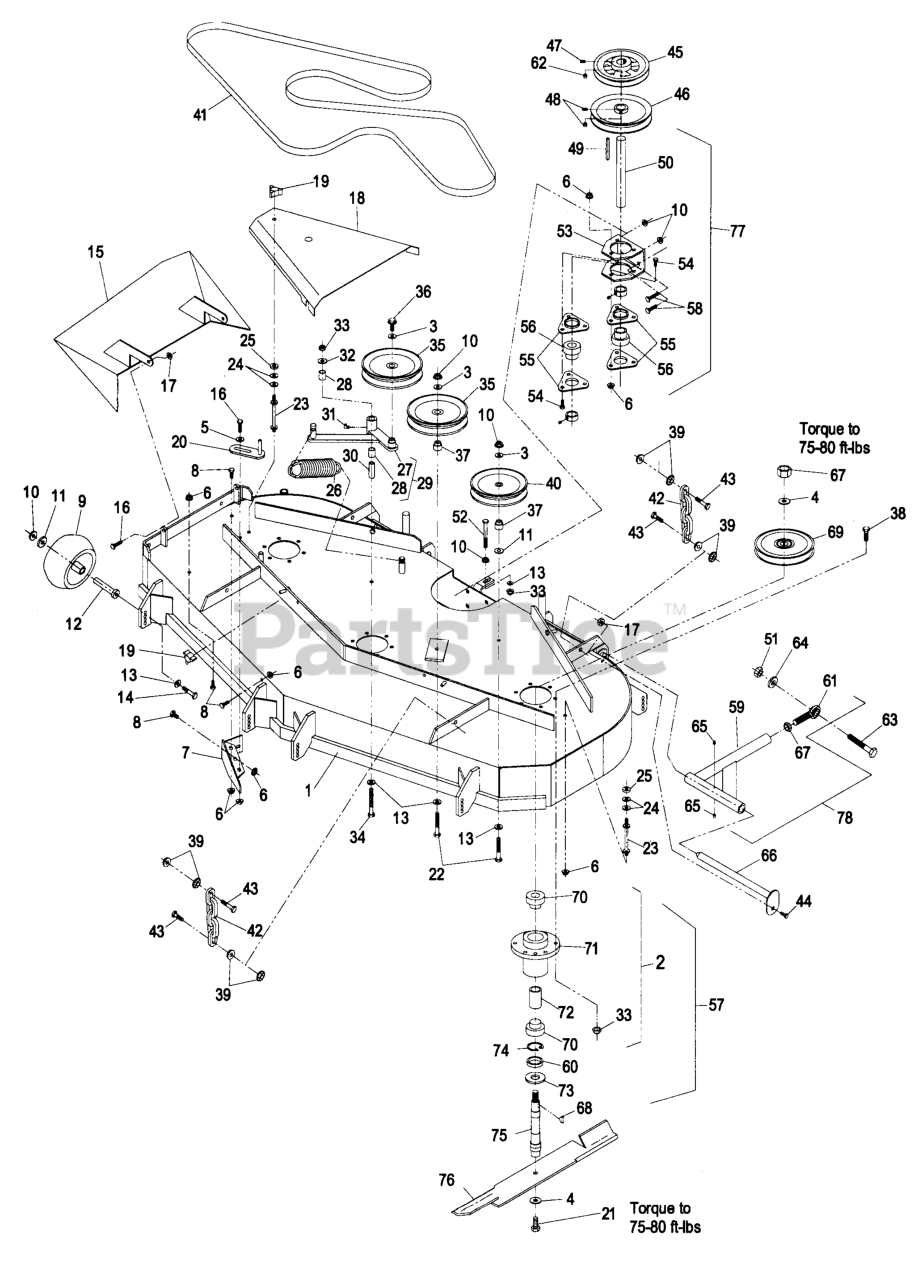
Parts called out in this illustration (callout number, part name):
4	WASHER-SPRING
5	WASHER-SPRING
7	WLD,BAFFLE DISCHARGE
9	ROLLER-SCALP, ANTI
12	BUSHING-ROLLER
18	SHIELD,BELT
19	KNOB-3 PRONG
20	GUIDE-BELT
23	STUD-SHIELD, BELT (SHORT)
28	SLEEVE-BEARING
30	BUSHING
37	BUSHING-IDLER
40	PULLEY-IDLER
41	BELT,BLADE DRIVE
42	CHAIN-LIFT, DECK
43	SCREW-CAP, HH
45	SHEAVE,BLADE DRIVE
46	SHEAVE,SPLIT STEEL
46	SHEAVE-SPLIT
48	SCREW-SET
49	KEY,MACH 1/4X1/4X2-5/8
50	JACKSHAFT,DECK DRIVE
53	BRACKET,JACKSHAFT
55	HOUSING-FLANGE
56	BEARING,W/COLLAR
57	SPINDLE HSG.ASSY.COMP.
60	SPACER-PULLEY/BEARING
61	BALLJOINT-SPHERICAL
62	SCREW-SET
66	PIN-STRUT
69	SHEAVE,BLADE DRIVE
70	BEARING
72	SPACER-BEARING
73	GUARD-BEARING, BOTTOM
75	SHAFT,SPINDLE 604
77	DK DR. BRG. ASSY
